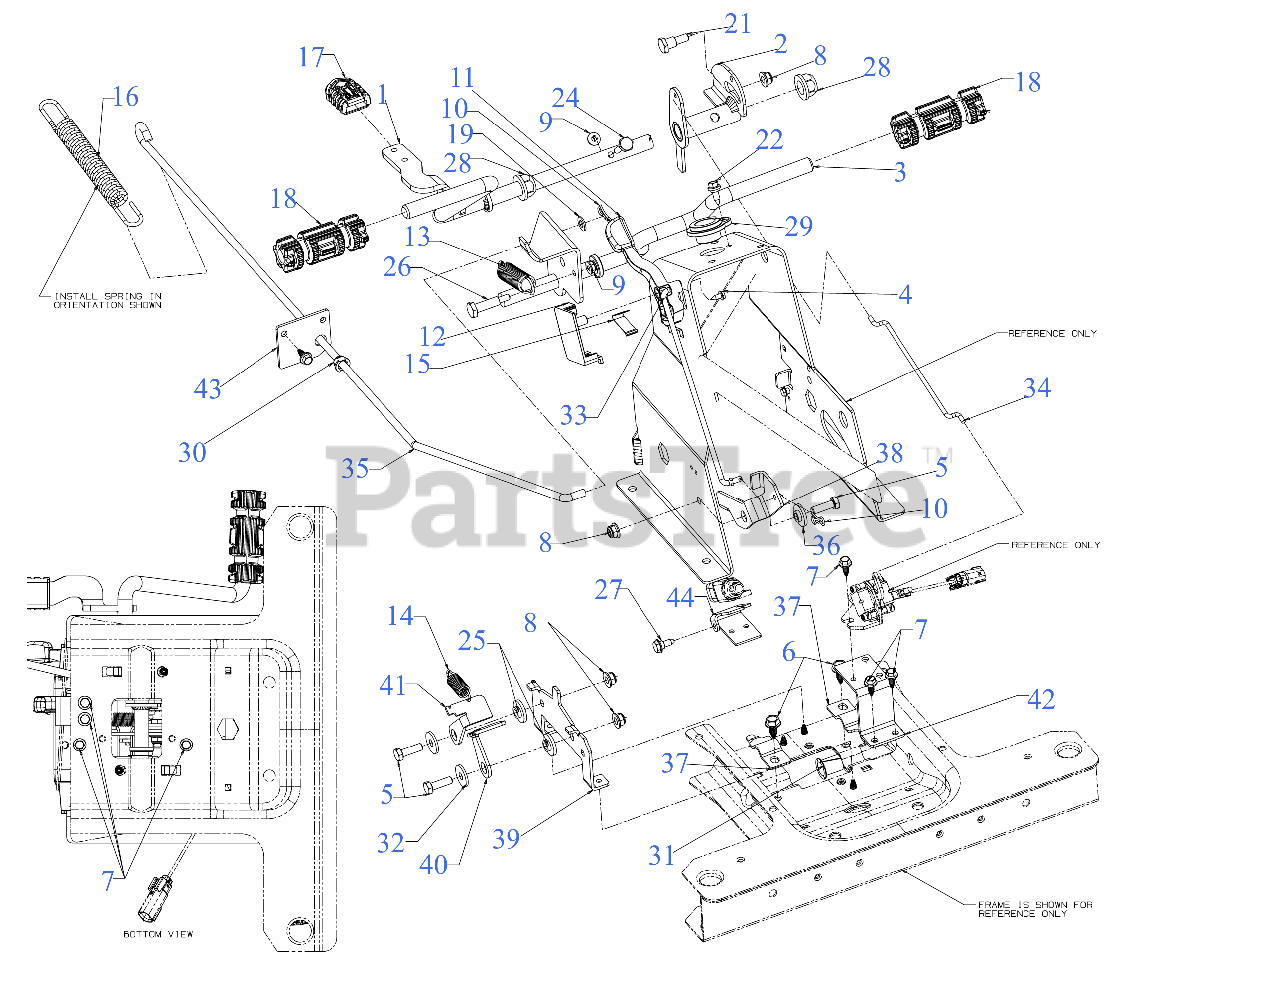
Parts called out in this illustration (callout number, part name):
2	PEDAL ASSEMBLY
4	HEX SCREW AB-TAP #10 x .50
5	SCREW 5/16-18 x 1.0 GR5
6	SCREW 5/16-18 x .750
7	SCREW 1/4-20X.625
8	FLANGE LOCK NUT 5/16-18
9	FLANGE LOCK NUT
10	BOW TIE COTTER PIN 1/4-5/16
11	PARK BRAKE LEVER
12	SPEED CONTROL COVER
13	EXTENSION SPRING
14	EXTENSION SPRING
15	SHIFT SPRING
16	EXTENSION SPRING 0.90 DIA x 8.14
17	REVERSE PEDAL PAD
18	BRAKE PEDAL PAD
19	FLAT WASHER .344 x .62
21	SHOULDER SCREW 5/16-18 x .62 GR2
22	SHOULDER SCREW
24	SHOULDER SCREW .375 x .148
25	SHOULDER SPACER (.315" x .50" x.14")
26	SHOULDER SCREW
27	SHOULDER SCREW .31
28	FLANGE BEARING
29	FLANGE BEARING
30	BUSHING .380 ID
31	FLANGE BEARING .626 x .938 x .875
32	THRUST BEARING (.323" x .985" x .1")
33	SPEED SELECT ROD
34	SWITCH ROD
36	SHOULDER SPACER
37	BRAKE SHAFT STRAP
38	PARK BRAKE BRACKET
40	REVERSE RETURN BRACKET
41	FORWARD RETURN BRACKET
